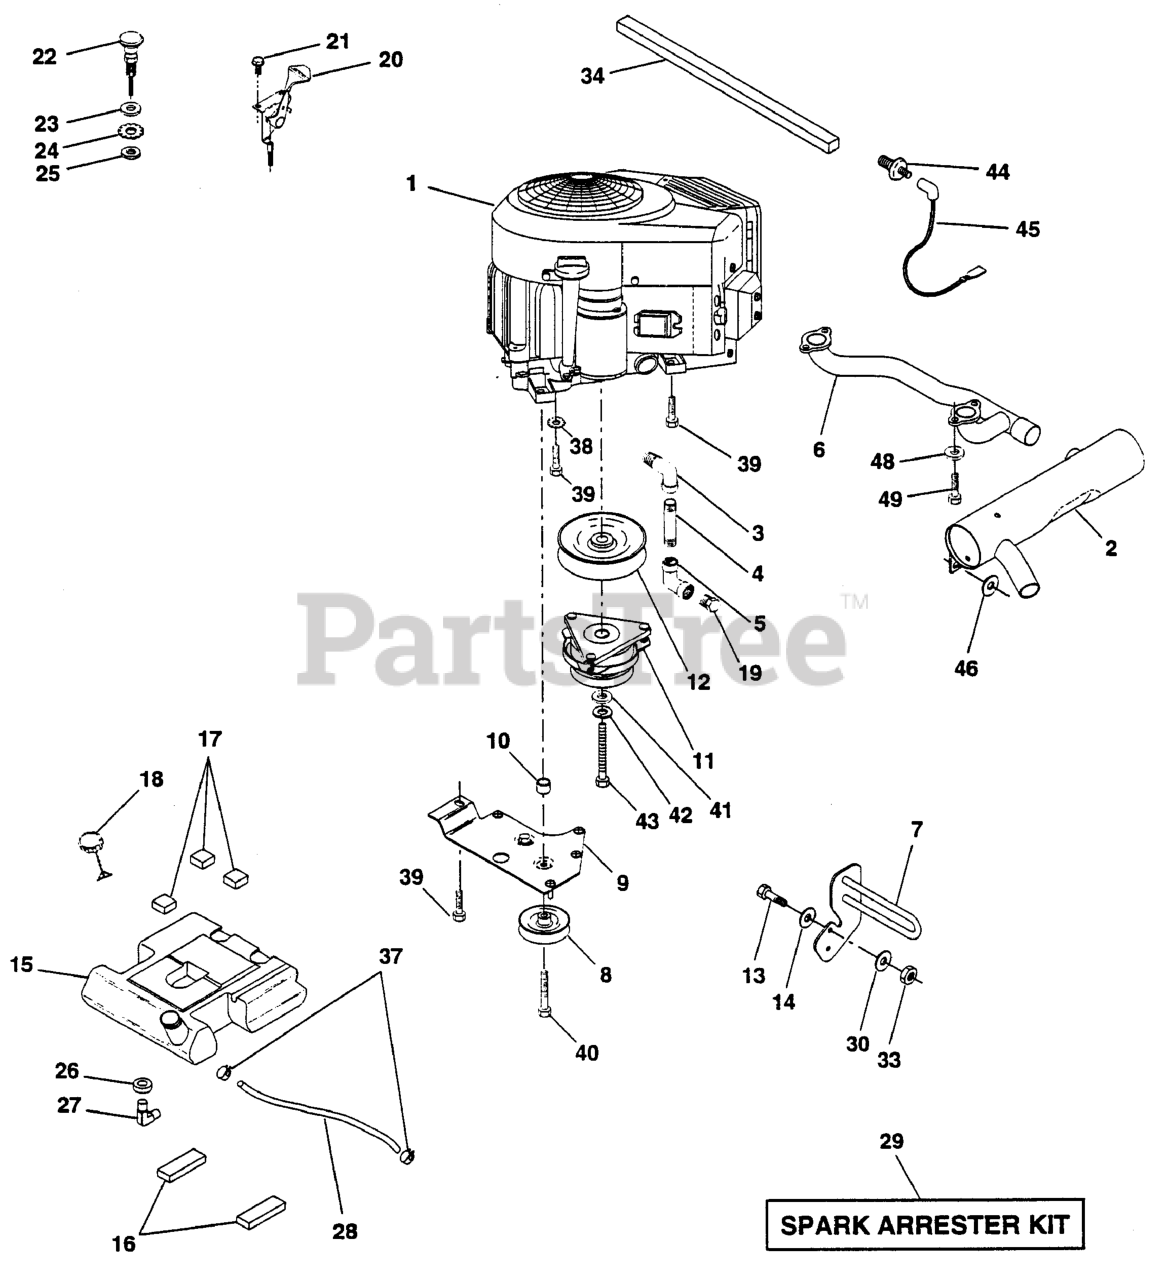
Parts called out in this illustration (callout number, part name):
1	Engine B&S, Model No. 351777
2	MUFFLER 20 VAN
3	STREET ELBOW LT NLA
4	Nipple Pipe 3/8NPT X 3 - 1/2
5	ELBOW
6	EXHAUST PIPE
7	MUFFLER GUARD
8	RP.IDLER GROOVED
9	STOP KEEPER
11	CLUTCH.ELECT.CVX.105 FT/LB.
12	PULLEY, ENGINE
13	BOLT
15	FUEL TANK
16	PAD IDLER TI
17	PAD-SPACER LT
18	FUEL CAP
19	PLUG T
20	THROTTLE CONTROL
21	SCREW LT
22	CHOKE CONTROL
23	WASHER
24	LOCKWASHER
25	NUT
26	BUSHING OUTLET T
27	STEM FUEL TANK
28	HOSE
29	SPARK ARRESTOR
30	Washer 13/32 x 1-1/4 x 7 Ga.
33	NUT
34	FOAM-STRIP LT
35	WASHER.LOCK.HVY.HLCL.SPR.5/16
37	HOSE CLAMP
38	LOCKWASHER
39	SCREW LT
40	Screw Thdrol 3/8 - 16 X 3 - 1/4
42	LOCKWASHER
43	BOLT
44	SWITCH, OIL PRESSURE
46	WASHER
